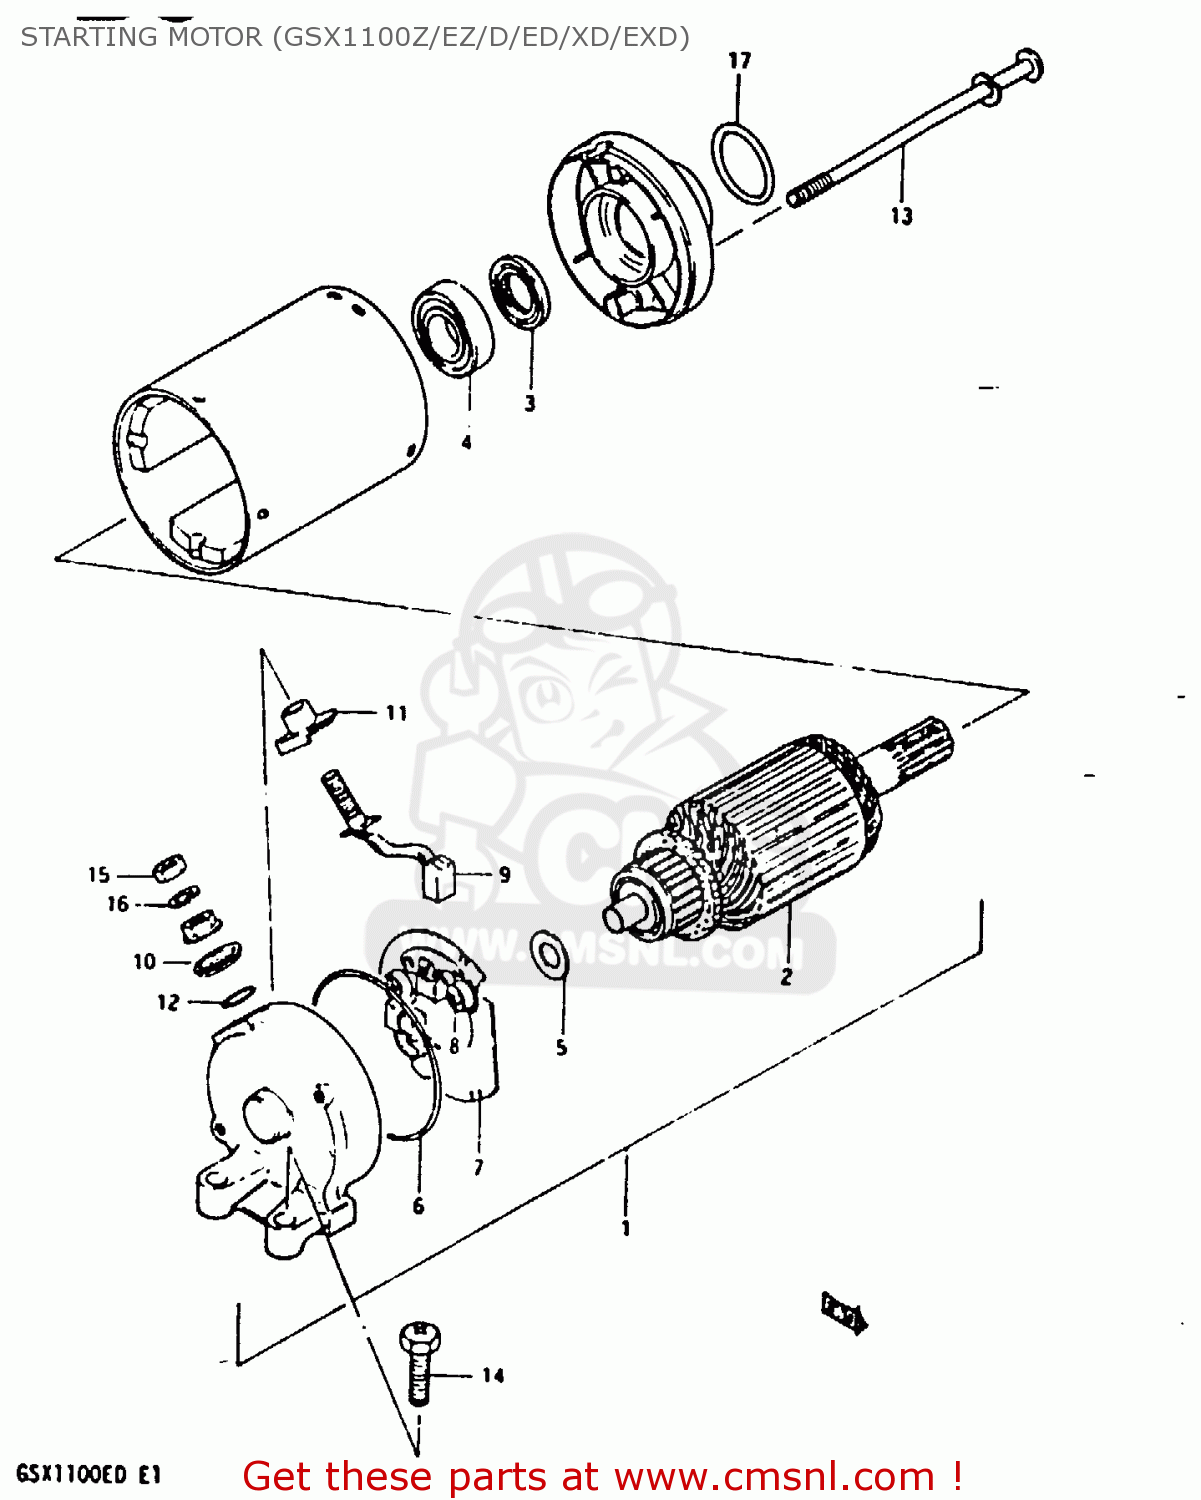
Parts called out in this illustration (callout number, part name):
1	MOTOR ASSEMBLY,STARTING
2	ARMATURE
3	SEAL,OIL
4	BEARING
5	SHIM,ARMATURE
6	O RING
7	HOLDER,BRUSH
8	SPRING
9	BRUSH (+)
10	BUSHING (1)
11	BUSH,NO.2
12	O-RING
13	BOLT,STARTING MOTOR HOUSING
14	SCREW (6X25)
15	NUT 6MM
16	LOCK WASHER
17	O RING(D:2,ID:24.5)
